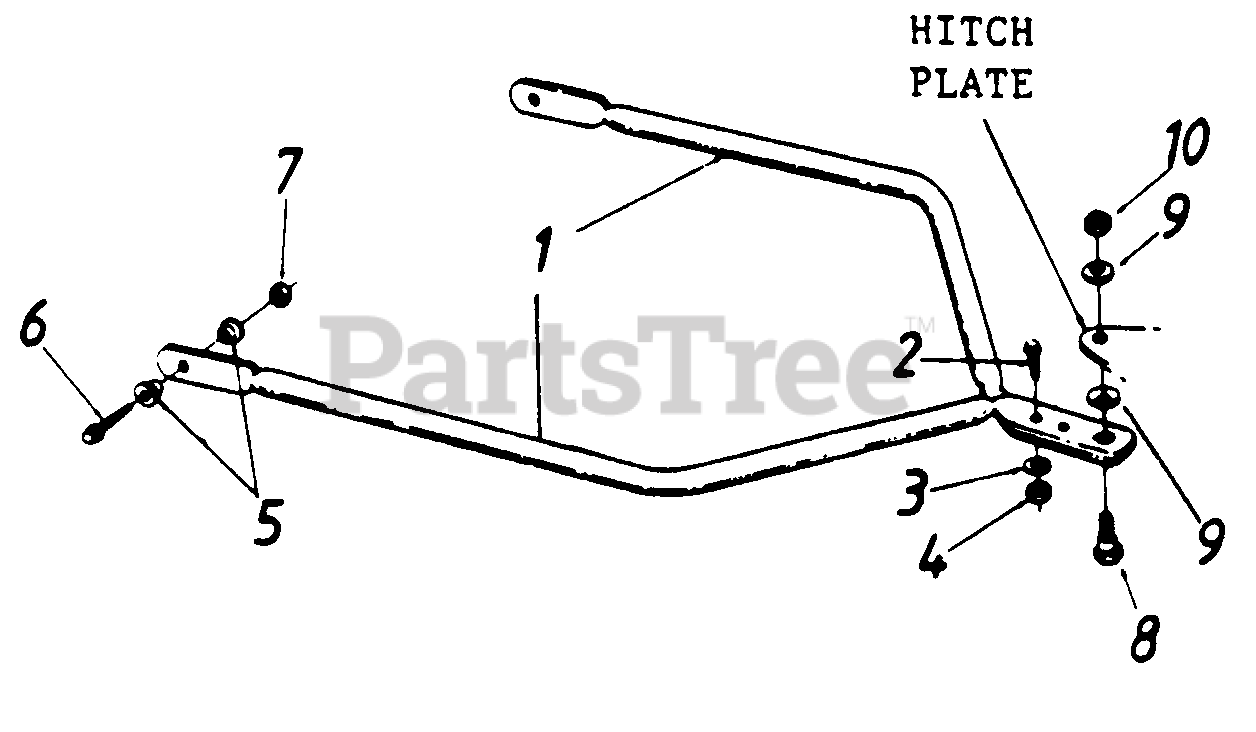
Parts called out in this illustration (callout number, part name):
3	L.-Wash. 1/4" I.D.
4	Hex Nut 1/4-20 Thd.
5	Shoulder Spacer
6	Hex Wash. Hd. Self-Tapp Scr. 5/16-18 x 1.0" L.
7	Hex Nut 5/16-18 Thd.
8	Shoulder Bolt
9	Bell-Wash. .39" I.D. x 12"
10	Hex Top Jam Nut 3/8-16 Thd.
